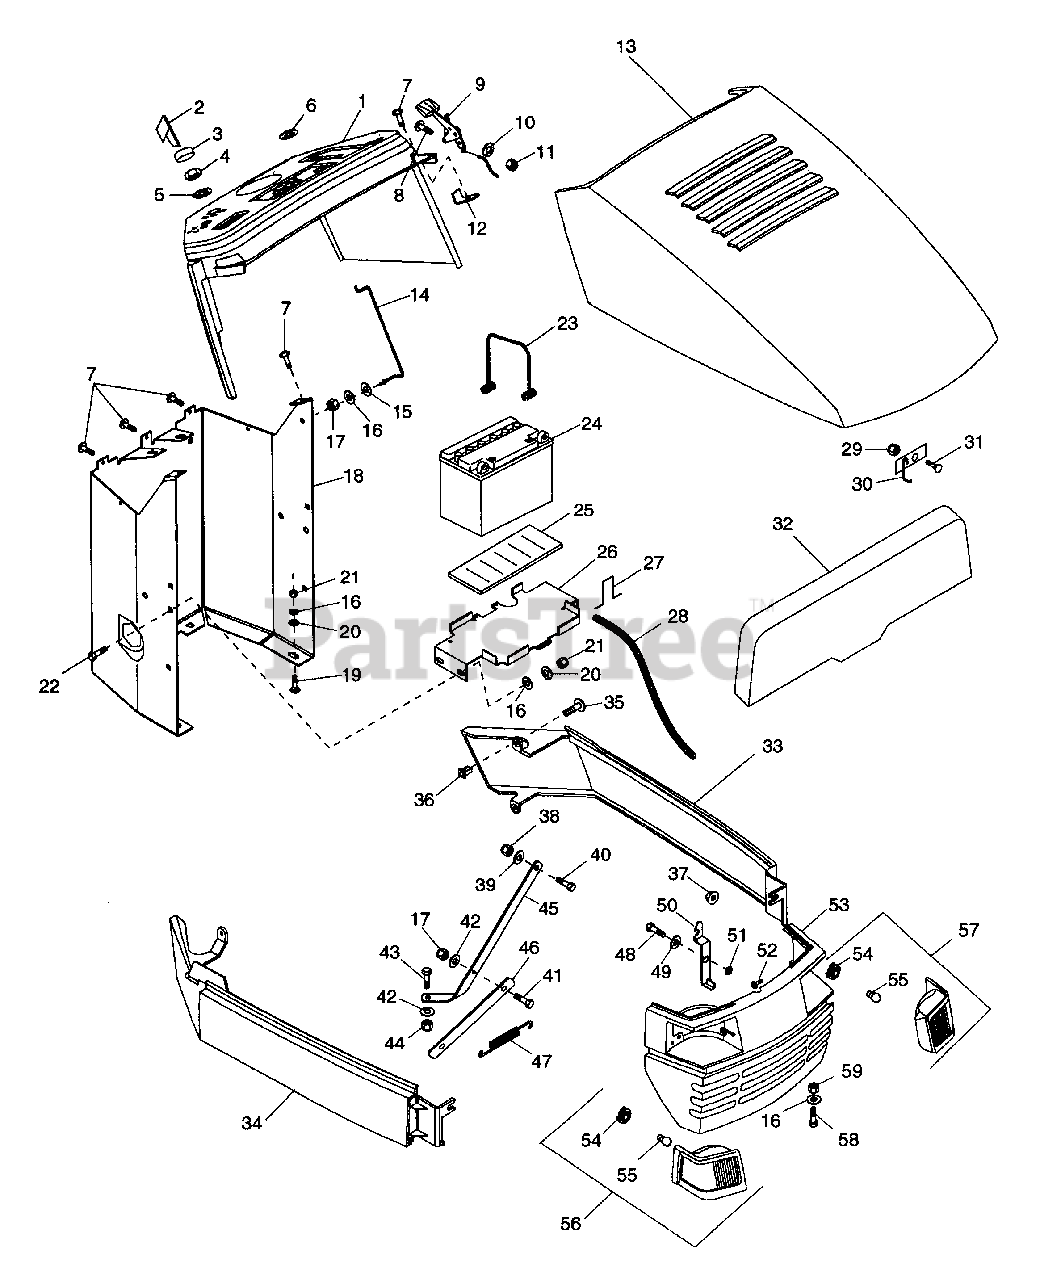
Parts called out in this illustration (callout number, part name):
1	DASH
2	KEY -W/CAP
3	CAP - IGNITION SWITCH
4	NUT- PANEL .562-24 GRECO
5	WSHR-LK-INT .563X.040 PL
6	WSHR-FL-STL .520X.827X.062 YZ
7	SCR-TAP 10-24X.375 CRPH 1A
8	SCR-MCH 10-24X.50 SLRH PL
9	THROTTLE CONTROL
10	WSHR-LK 10X.047 MED PL
11	NUT-HEX 10-24 PL
13	HOOD- ORANGE
14	HOOD PROP ROD
15	WAVE WASHER .390X.655X.110
16	WSHR-FL-STL.312X.734X.065PL
17	NUT-LK-CTR .250-20 PL
18	DASH TOWER
19	BLT-RDHDSQNK.31-18X.75GR5SHTPL
20	WSHR-LK .312X.097 PL HVY
21	NUT-HEX .312-18
22	BLT-HEX .31-18X.63 PL GR 2
23	BATTERY STRAP
24	BATTERY
25	BATTERY TRAY
26	BATTERY SUPPORT
27	HOOK
28	DRAIN HOSE
29	NUT-FLG. .312-18 PL
30	HOOD CATCH ASSY
31	BLT-RDHDSQNK .312-18X.62SHTPL
32	BAFFLE- HOOD
32	BAFFLE- HOOD 15/16.5HP
33	L.H. UPPER PANEL
34	R.H. UPPER PANEL
35	SCR-TAP 10-12X.50 CRPH PL A BL
36	PLASTIC GROMMET
37	NUT-SELF-THRDNG FITS.25 STUDPL
38	NUT-HEX .375-16
39	WSHR-LK .375X.094 MED PL
40	BLT-HEX .38-16X1.00 PL
41	BLT-HEX .25-20X.50 PL GR2
42	WSHR-FL-STL.406X.812X.065PL
43	BLT-HEX .38-16X.75 PL GR2
44	NUT-LK-CTR .375-16 GR A PL
45	GRILLE SUPPORT
46	GRILLE BRACE
47	SG-TENS .035X.45X2.75 WLD 3.5
48	SCR-TAP 12-24X.75 HWH PL TR
49	WSHR-FL-STL .281X1.250X.048PL
50	HOOD LATCH
51	BSHG-FLG .500X.625X.148
52	SCR-TAP 10-12X.50 CRPH PL A
53	GRILL
54	LAMP SOCKET
55	HEADLIGHT BULB, 1156
56	HEADLIGHT- R.H.
57	HEADLIGHT- L.H.
58	BLT-HEX .31-18X.75 PL GR5
59	NUT-LK .312-18 GR A PL
